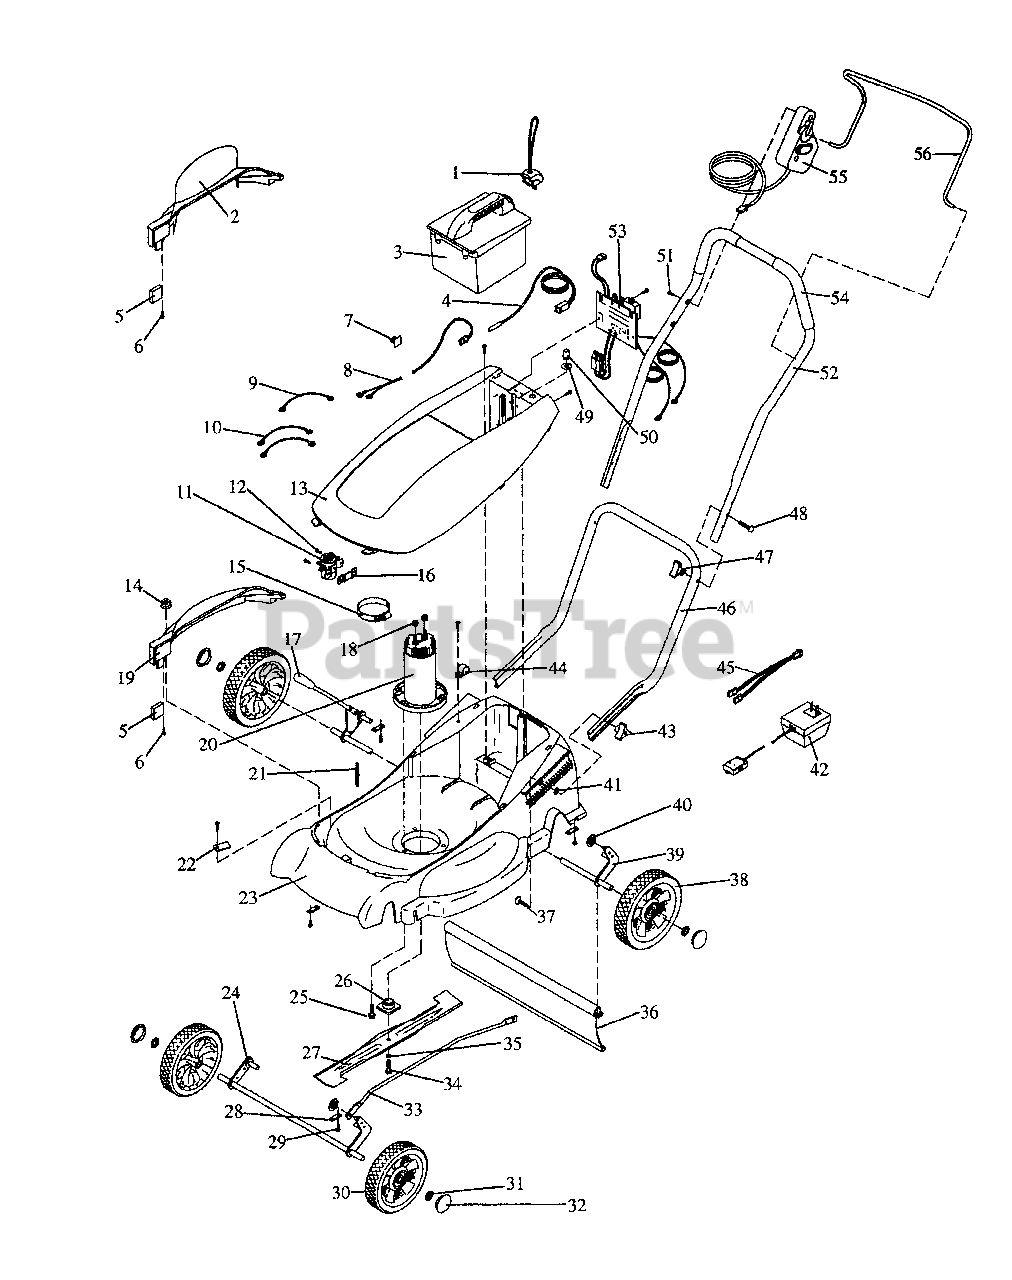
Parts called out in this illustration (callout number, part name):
2	Discharge Chute
3	Battery Pack Assembly
4	Interlock Switch Assembly
7	Cord Clip
8	Circuit Board Wire Assembly
9	Solenoid Wire Assembly
10	Solenoid Wire Assembly
11	Solenoid
12	Solenoid Screw
13	Mower Cover
15	Solenoid Clamp
16	Solenoid Bracket
17	Height Adjustor Handle
18	Motor Nut
19	Mulching Cover
20	Motor
21	Chute Stud
22	Interlock Retainer
23	Mower Deck
24	Height Adjustor, Front
25	Bolt, Motor
26	Blade Adaptor
28	Axle Retainer
30	Front Wheel
31	Wheel Retainer
33	Height Adjustor Link
34	Blade Mounting Bolt
35	Washer, Split Ring
36	Drag Shield
37	Lower Handlebar Bolt
38	Rear Wheel
39	Height Adjustor, Rear
40	Link Retainer
41	Bolt Retainer
42	Charger
43	Handlebar Knob
44	Wire Clamp
45	Harness, Battery Charger
46	Lower Handlebar
47	Handlebar Knob
48	Handlebar Bolt
49	Circuit Breaker Label
50	Circuit Breaker Boot
51	Handlebar Screw
52	Upper Handlebar
53	Motor Control
54	Foam Grip
55	Deadman Control Assembly
56	Wire, Bail Assembly
